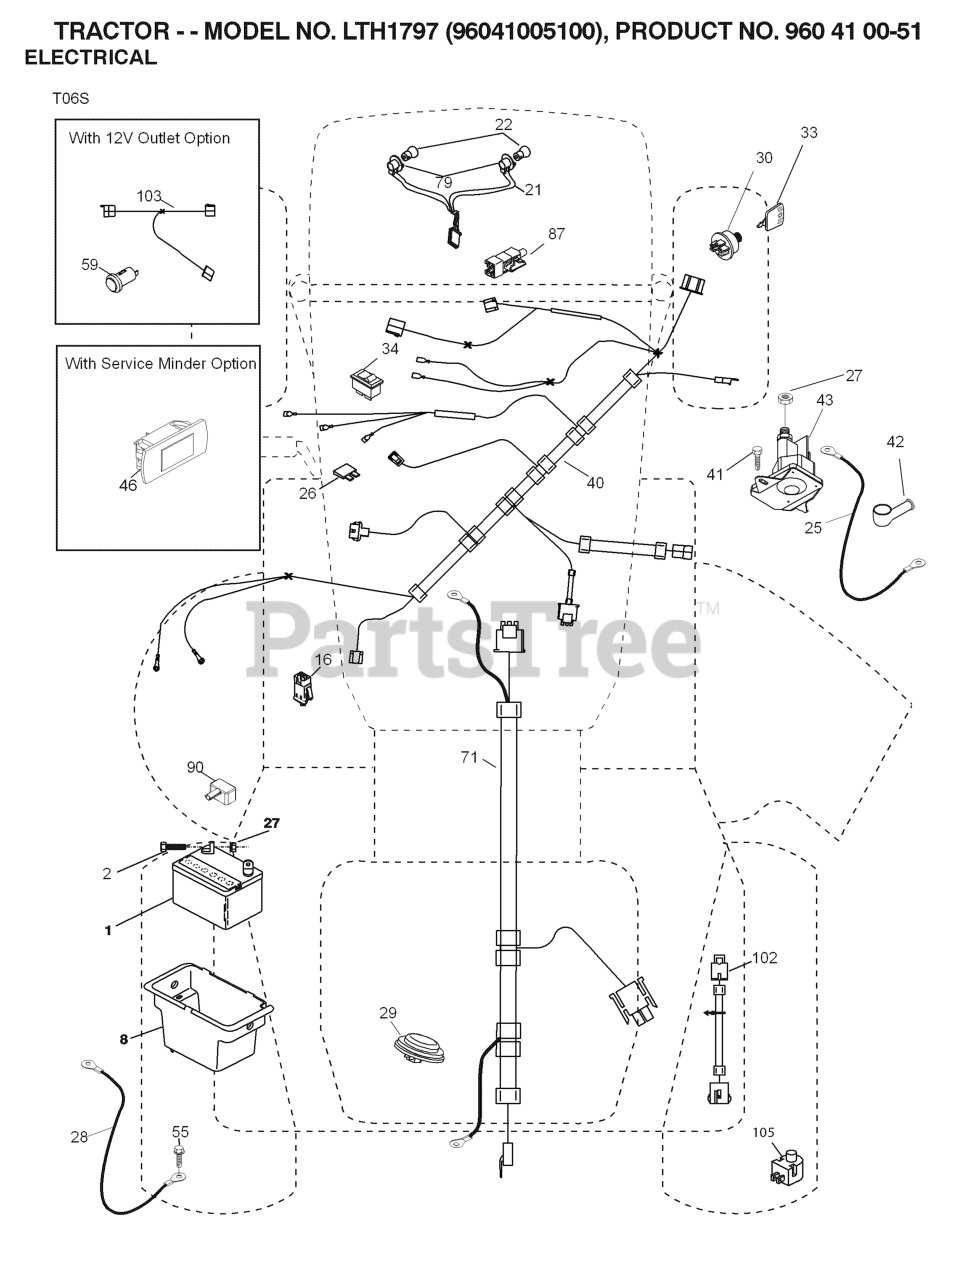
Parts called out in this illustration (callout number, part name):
1	BATTERY 12V .35 AMP
2	BOLT.HEX.1/4.X.3/4.DICHROMATE
8	BOX.BATTERY.MNT.REAR.L
16	SWITCH INTERLOOK PUSH-IN
21	HARNESS.LIGHT W/4152J BULBS
25	CABLE.STARTER.6GA.RED.
26	FUSE 20AMP
27	NUT
28	CABLE.BLACK.18"REAR.BA
29	SWITCH.SEAT.DELTA.OPC.
30	SWITCH.IGN.DELTA.W.LGH.ROS
33	KEY MLD GEN DELTA
40	HARNESS IGN. DASH
41	SCREW
42	TERMINAL COVER
43	SOLENOID.W/BRASS.PLUNGER
55	SCREW 5/16"
71	HARNESS.IGN.CHASS.TEX.REAR.BAT
79	BULB HOLDER ASM.
87	SWITCH.INTRLCK.CLUTCH.
90	COVER, TERMINAL BATTERY
102	HARNESS PIGTAIL PCH TEX ROS
105	REVERSE SWITCH
